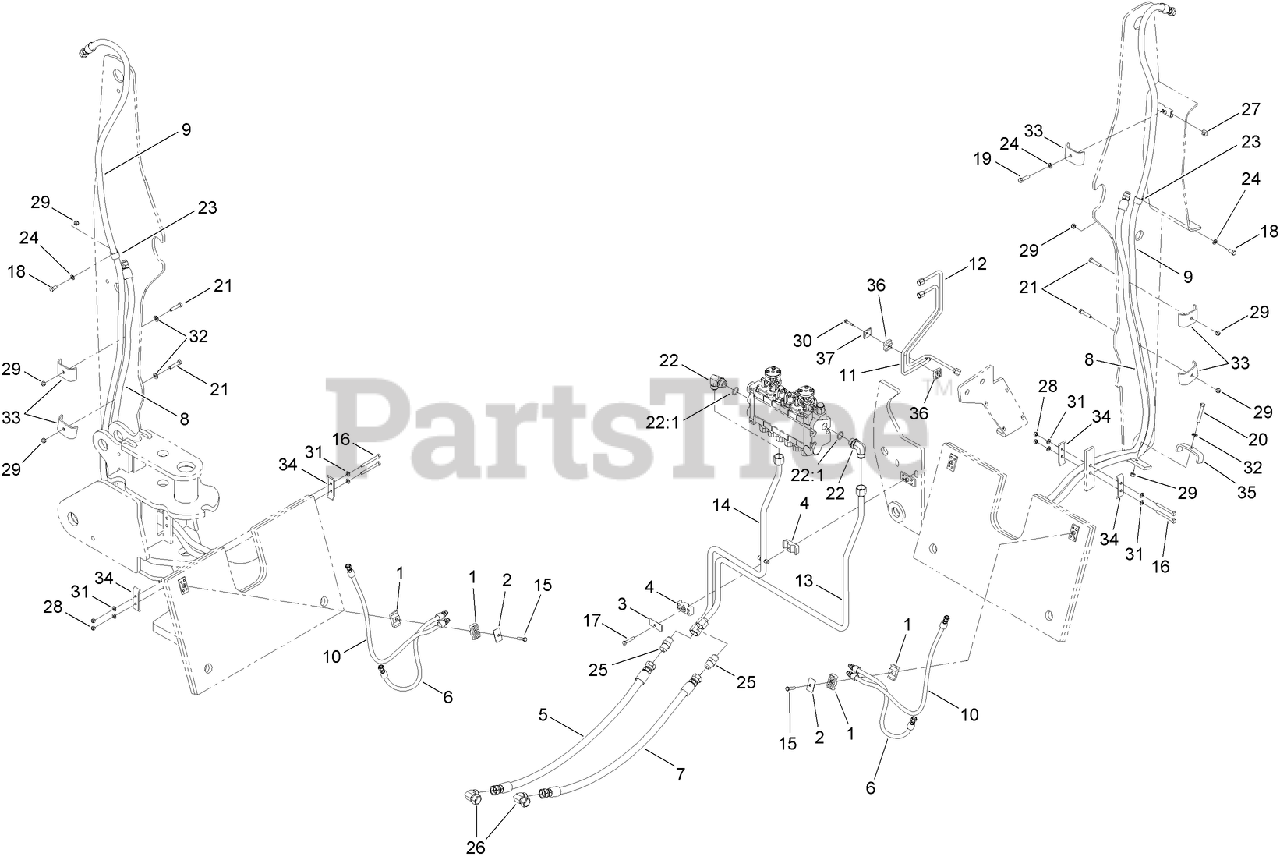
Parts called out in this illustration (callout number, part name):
1	CLAMP-TUBE
2	COVERPLATE
3	PLATE-COVER
4	CLAMP-TUBE
5	HOSE ASM
6	HOSE ASM (LEFT CYLINDER)
7	HOSE ASM (VALVE)
8	HOSE ASM (DIPPER)
9	HOSE ASM (DIPPER)
10	HOSE ASM
11	TUBE ASM
12	TUBE ASM
13	TUBE ASM
14	TUBE ASM
15	SCREW-HH
16	SCREW-HH
17	SCREW-HH
18	SCREW-HH
19	SCREW-HH
20	SCREW-HH
21	SCREW-HH
22	FITTING-ELBOW, 90 DEG
22:1	O-RING
23	CLAMP-R
24	WASHER-LOCK
26	FITTING-ELBOW, 90
27	NUT-SQUARE
28	NUT-HEX
29	NUT-HEX
30	SCREW-HH
31	WASHER-FLAT
32	WASHER-FLAT
33	RETAINER-HOSE
34	STRAP-ANGLE
35	CLAMP-HOSE, RETAINER
36	CLAMP-TUBE
37	PLATE-CLAMP, RETAINER
